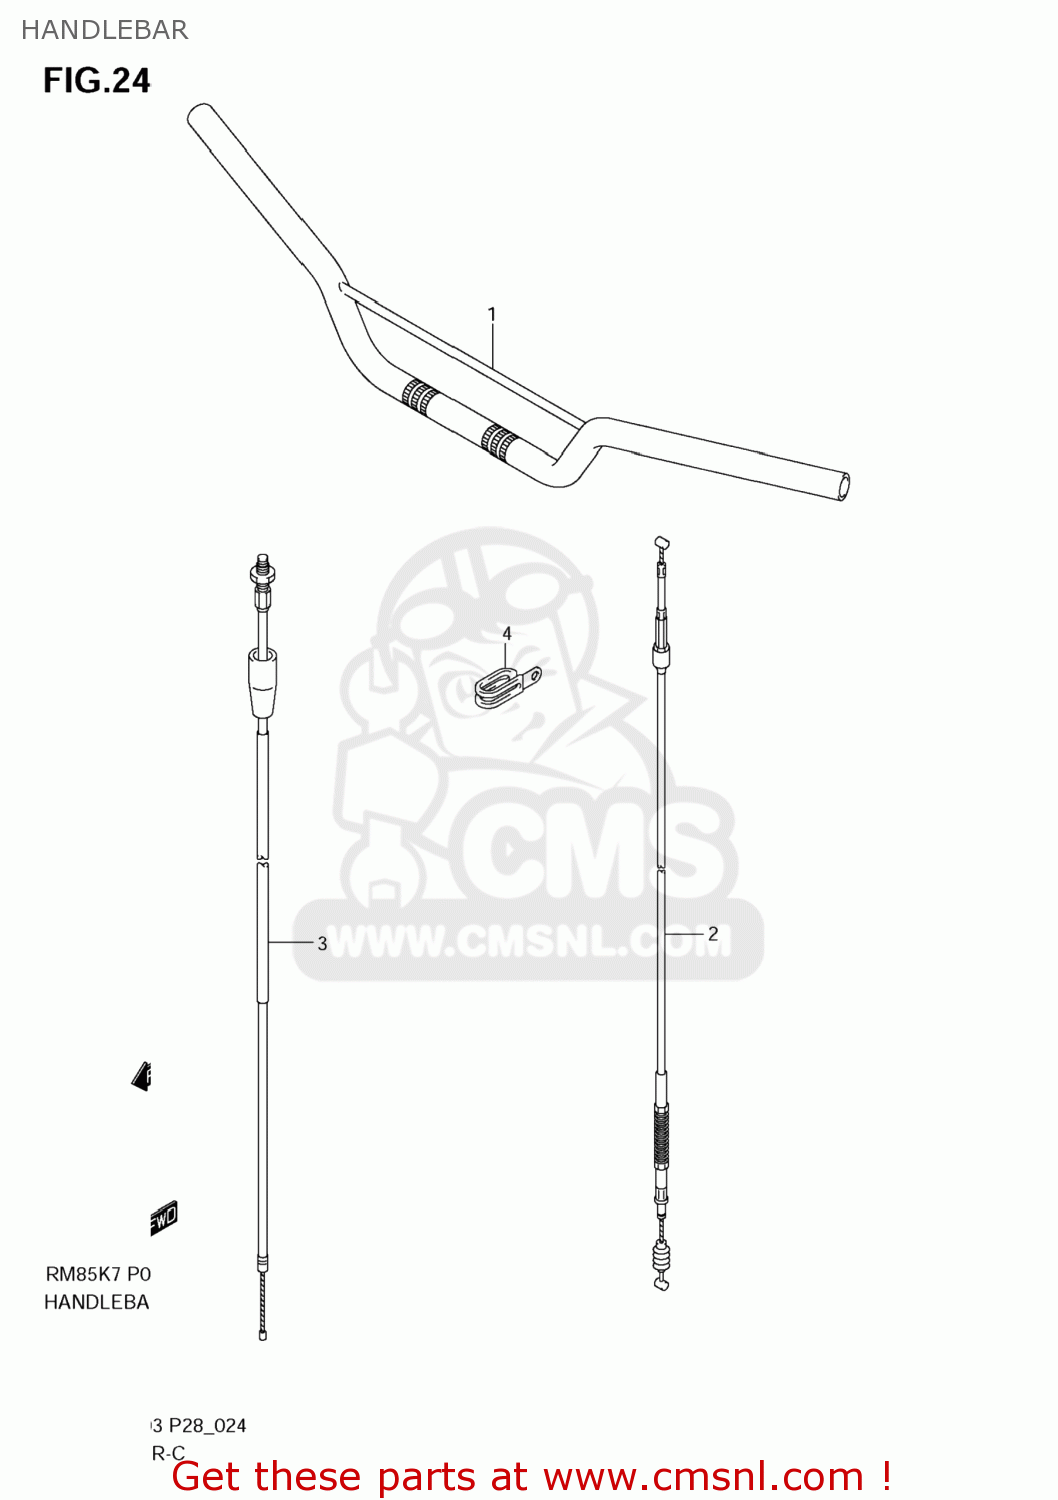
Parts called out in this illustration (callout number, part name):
1	HANDLEBAR COMP
2	CABLE ASSY,CLUTCH
3	CABLE ASSY,THROTTLE
4	CLAMP
